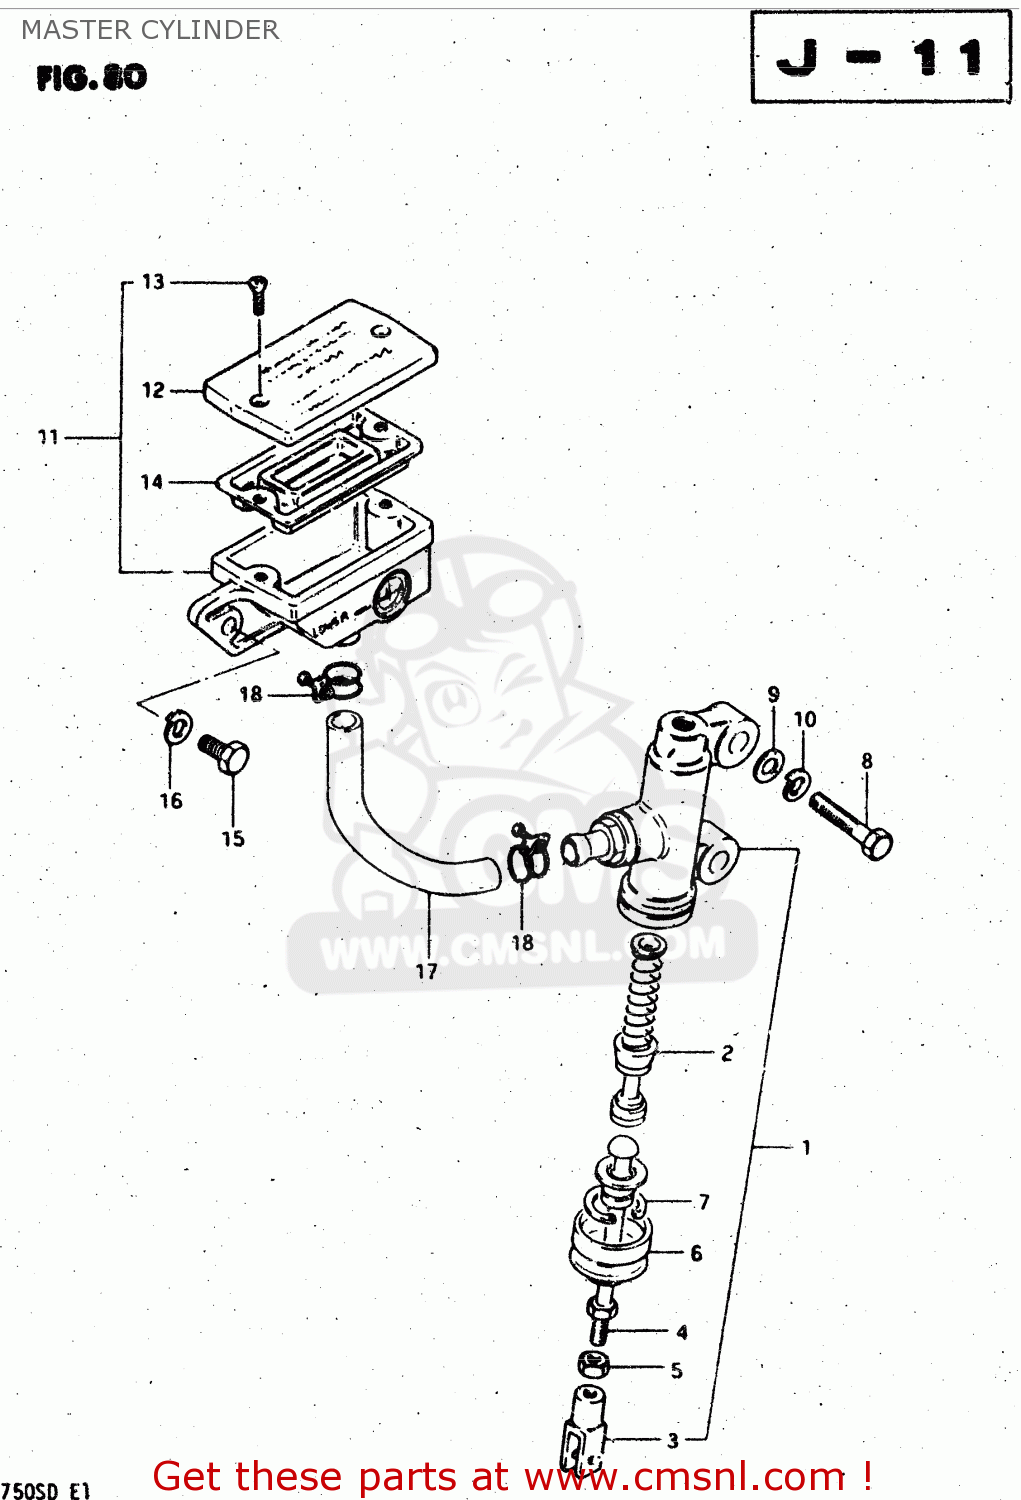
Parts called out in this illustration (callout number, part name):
1	CYLINDER ASSEMBLY,REAR MASTER
2	PISTON/CUP SET
3	YOKE
4	LOD,PUSH
5	NUT,MASTER CYLINDER
6	BOOT
7	CIRCLIP
8	BOLT (8X30)
9	WASHER
10	LOCK WASHER
11	RESERVOIR TANK ASSY
12	CAP
13	SCREW
14	15
15	BOLT, UPPER
16	LOCK WASHER
17	HOSE,RESERVOIR TANK
18	CLAMP
